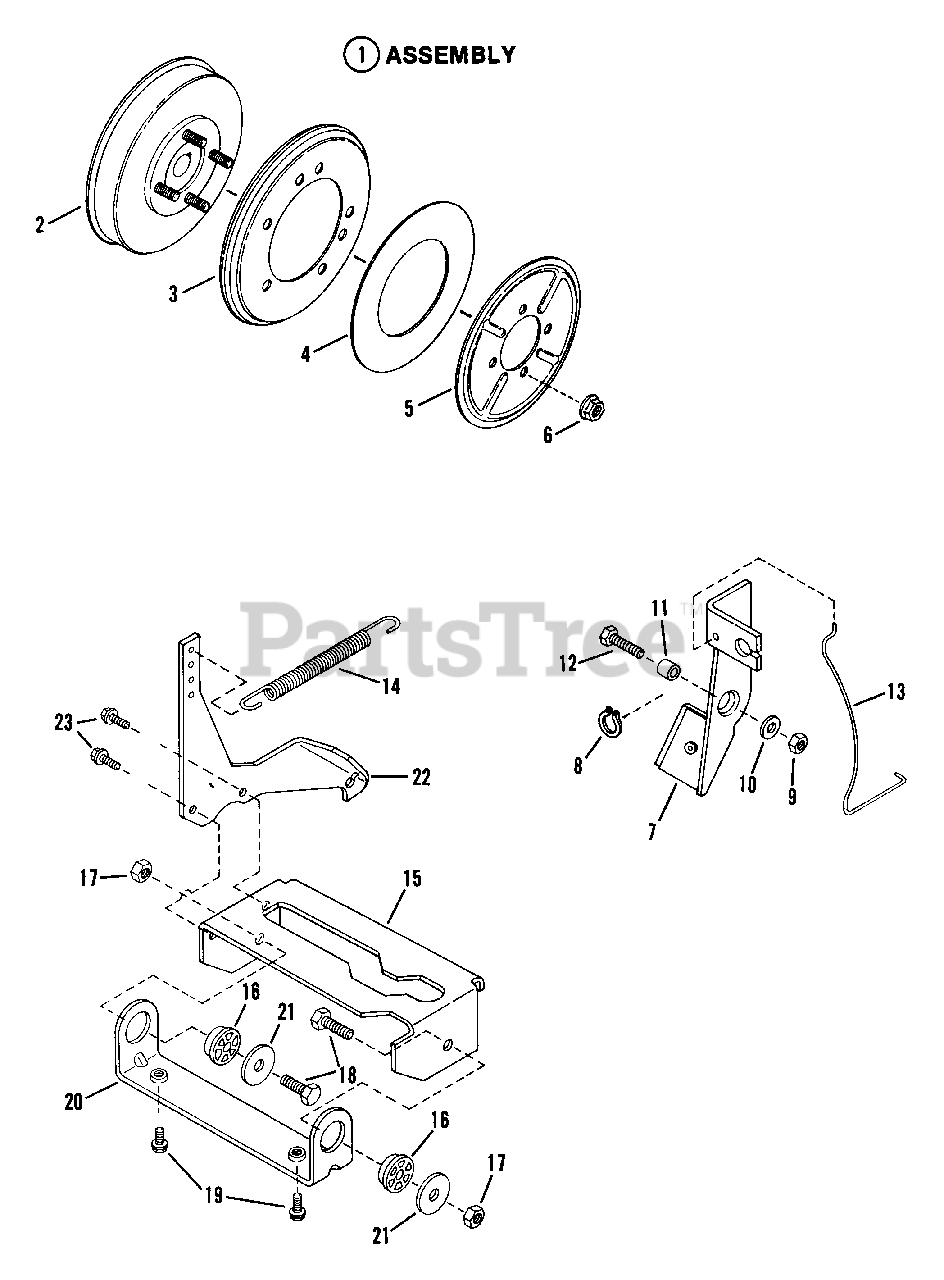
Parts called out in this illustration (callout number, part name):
1	ASSEMBLY, Smooth Clutch
2	HUB, Driven Disc
3	DISC, Driven
4	WASHER, Thrust
5	PLATE
6	NUT, 5/16-18 Hex Flange Lock
7	ASSEMBLY, Brake Lever
8	RING, Retaining
9	NUT, 1/4-28 Hex Top Lock
10	WASHER, 1/4 Flat
11	SPACER
12	SCREW, 1/4-28 x 1" Hex Head Cap
13	SPRING, Brake Return
14	SPRING, Clutch Brake
15	LIFT, Yoke
16	BEARING, Yoke
17	NUT, 5/16-24 Hex Center Lock
18	SCREW, 5/16-24 x 3/4" Hex Head Cap
19	SCREW, 3/8-16 x 1/2" Self-Tapping
20	COLLAR, Yoke
21	WASHER, 5/16 Flat
22	ARM, Yoke
23	SCREW, 5/16-18 x 1/2" Self-Tapping
